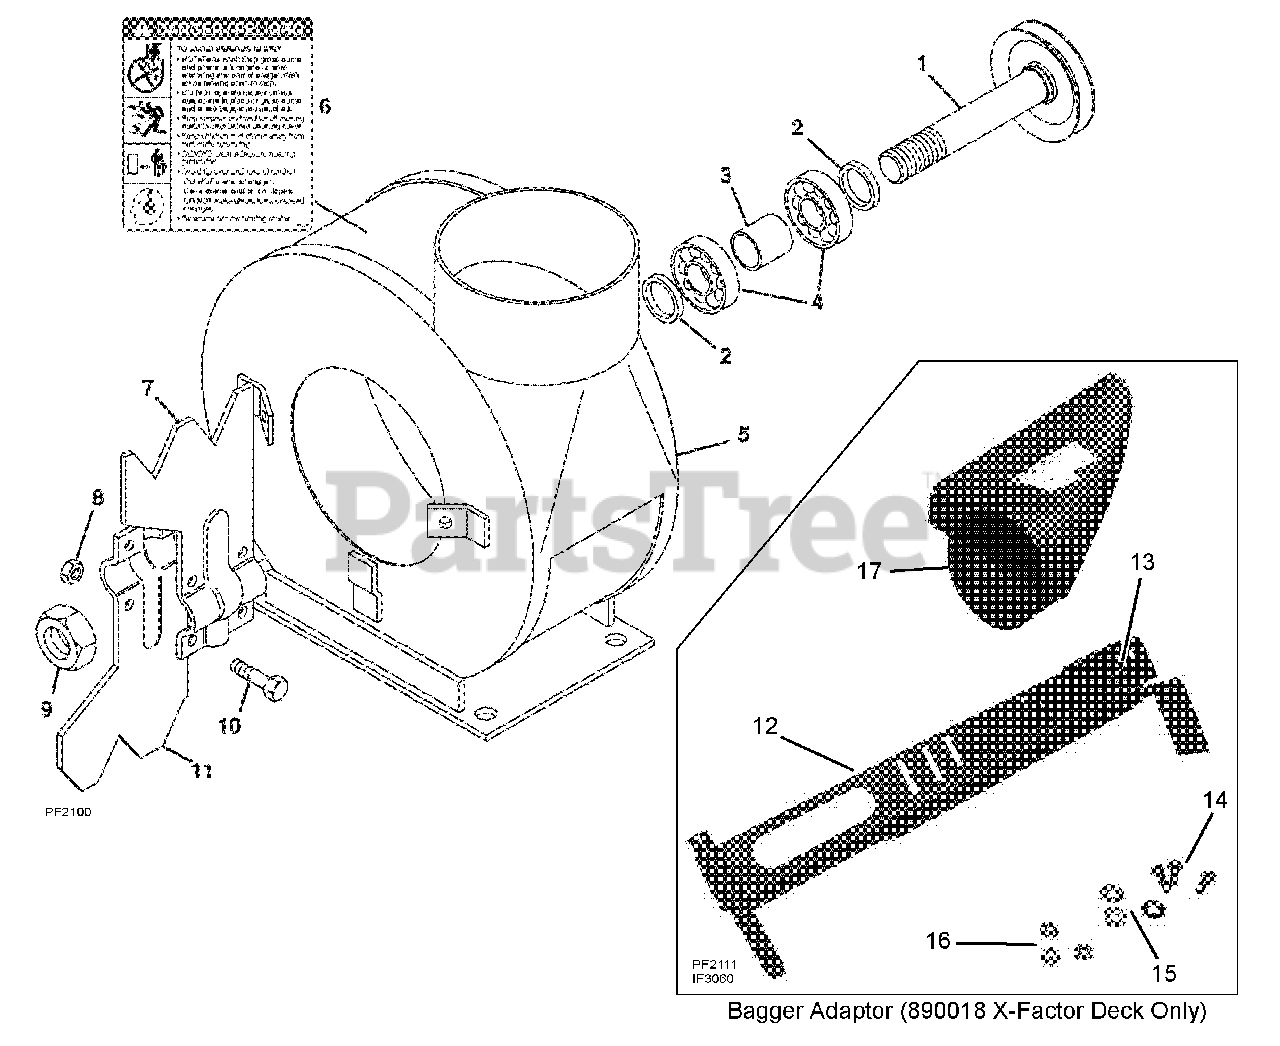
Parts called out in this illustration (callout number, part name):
1	Weldment-Spindle
2	Washer-Flat-Steel 1.015 x 1.5 x .125
4	Bearing-Ball 1.0 x 2.0 x .56
5	Weldment, Fan Housing
6	Decal-Danger
7	Blade-Fan
8	Nut-Locking-Center .31-18
9	Nut-Locking-Jam 1.0-14
10	Bolt-Hex .31-18 x .75 Grade 5
11	Blade-Fan
12	Adapter, PM320 X-Factor Deck
13	Plunger Pull Pin 1/2-13
14	Hex Bolt, 3/8-16 x 1-1/4 Grade 5
15	Washer, Flat Steel 7/16 x 1
16	Nut, Nulon Locking, 3/8-16
17	Boot, 60" Bagger
